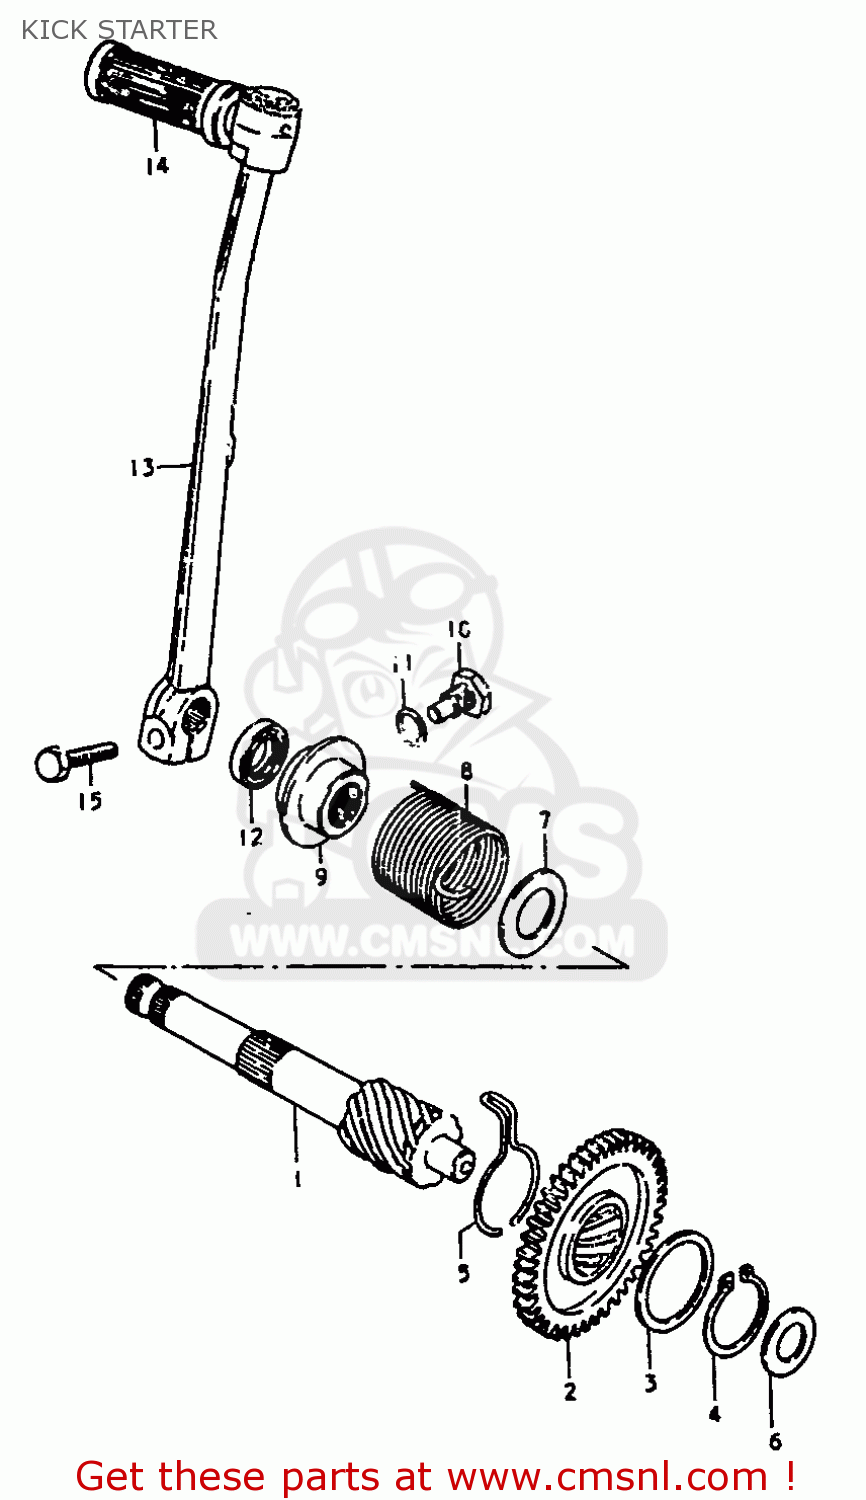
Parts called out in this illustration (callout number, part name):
1	SHAFT,KICK STARTER
2	GEAR,KICK STARTER DRIVE
3	WASHER
4	CIRCLIP
5	RETAINER,SNAP
6	WASHER
7	WASHER(16X30X1)
8	SPRING
9	LIFTER,KICK STARTER
10	BOLT(10X17)
11	GASKET(10X14X3.6) (NAS)
12	SEAL,OIL(14X24X6)
13	LEVER ASSEMBLY,KICK STARTER
14	RUBBER,KICK STARTER PEDAL
15	BOLT
